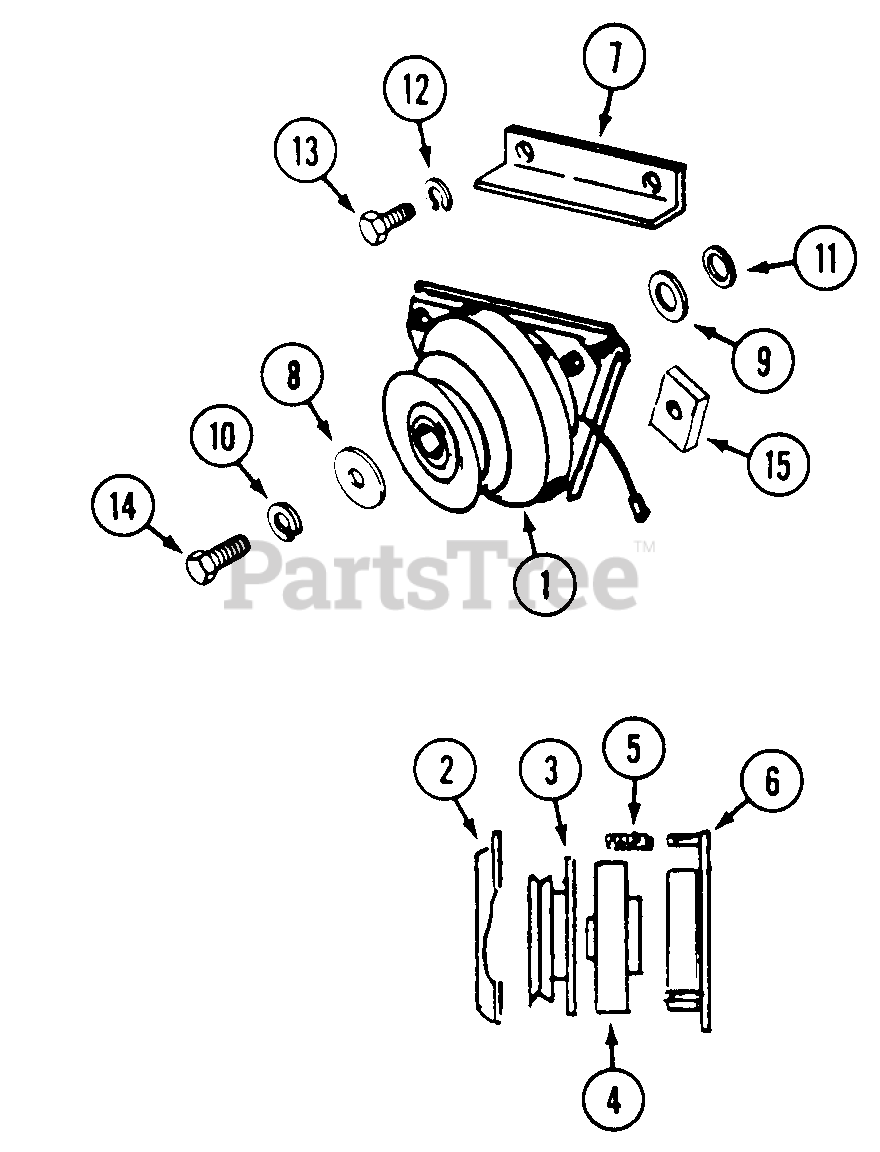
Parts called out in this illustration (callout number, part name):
1	CLUTCH ASSEMBLY
2	BRAKE - clutch
3	ARMATURE - clutch
4	ROTOR - clutch
5	KIT - spring and nut (3 each)
6	COIL - clutch
7	BRACKET - clutch stop
8	WASHER - retaining
9	WASHER - 1"
10	LOCKWASHER - 3/8"
11	WASHER - 1-1/8"
12	LOCKWASHER - 7/16"
13	BOLT - 7/16"-14 x 3/4"
14	BOLT - 3/8"-24 x 1-1/2"
15	BRACKET - clutch stop
